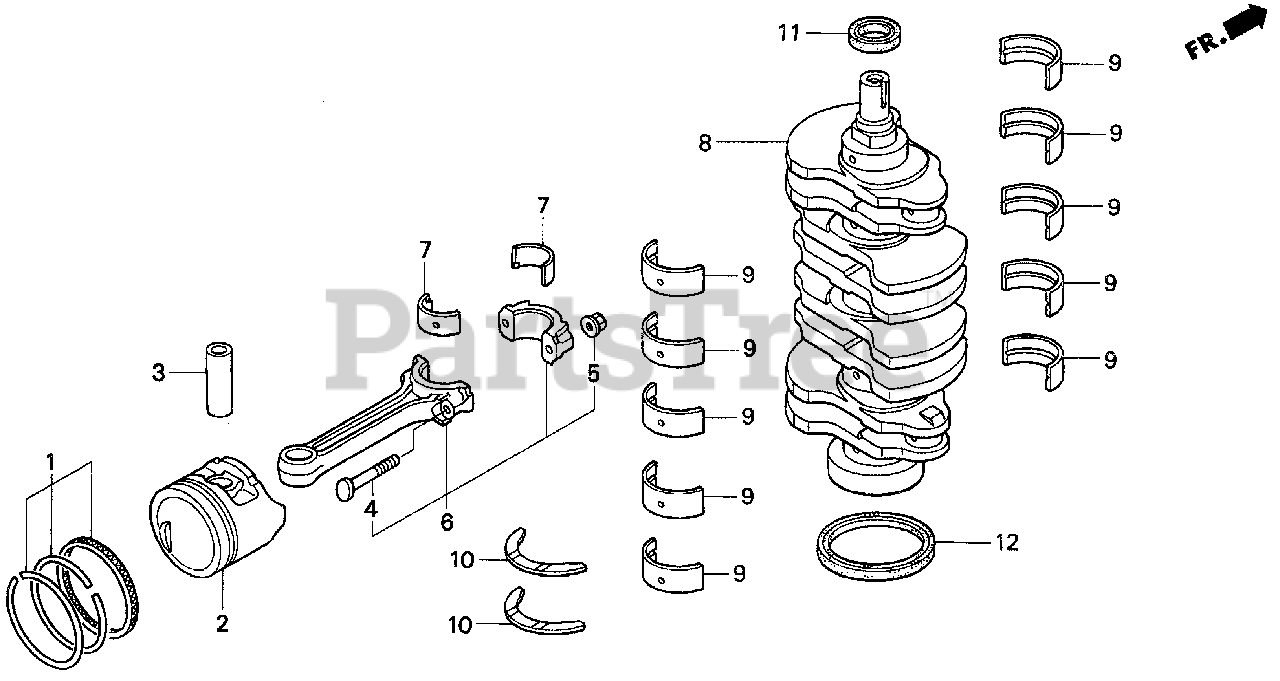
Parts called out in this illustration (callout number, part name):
1	RING SET, PISTON (STD)
1	RING SET, PISTON (OS 0.25)
2	PISTON (OS 0.25)
3	PIN, PISTON
4	BOLT, CONNECTING ROD
5	NUT, CONNECTING ROD
6	ROD, CONNECTING
7	BEARING A, CONNECTING ROD (BLUE) (DAIDO)
7	BEARING B, CONNECTING ROD (BLACK) (DAIDO)
7	BEARING C, CONNECTING ROD (BROWN) (DAIDO)
7	BEARING D, CONNECTING ROD (GREEN) (DAIDO)
7	BEARING E, CONNECTING ROD (YELLOW) (DAIDO)
7	BEARING F, CONNECTING ROD (PINK) (DAIDO)
7	BEARING G, CONNECTING ROD (RED) (DAIDO)
8	CRANKSHAFT
9	BEARING A, MAIN (BLUE) (TAIHO)
9	BEARING B, MAIN (BLACK) (TAIHO)
9	BEARING C, MAIN (BROWN) (TAIHO)
9	BEARING D, MAIN (GREEN) (TAIHO)
9	BEARING E, MAIN (YELLOW) (TAIHO)
9	BEARING F, MAIN (PINK) (TAIHO)
9	BEARING G, MAIN (RED) (TAIHO)
10	WASHER, THRUST (TAIHO)
11	OIL SEAL (31X46X7)
12	OIL SEAL (98X80X10) (NOK)
